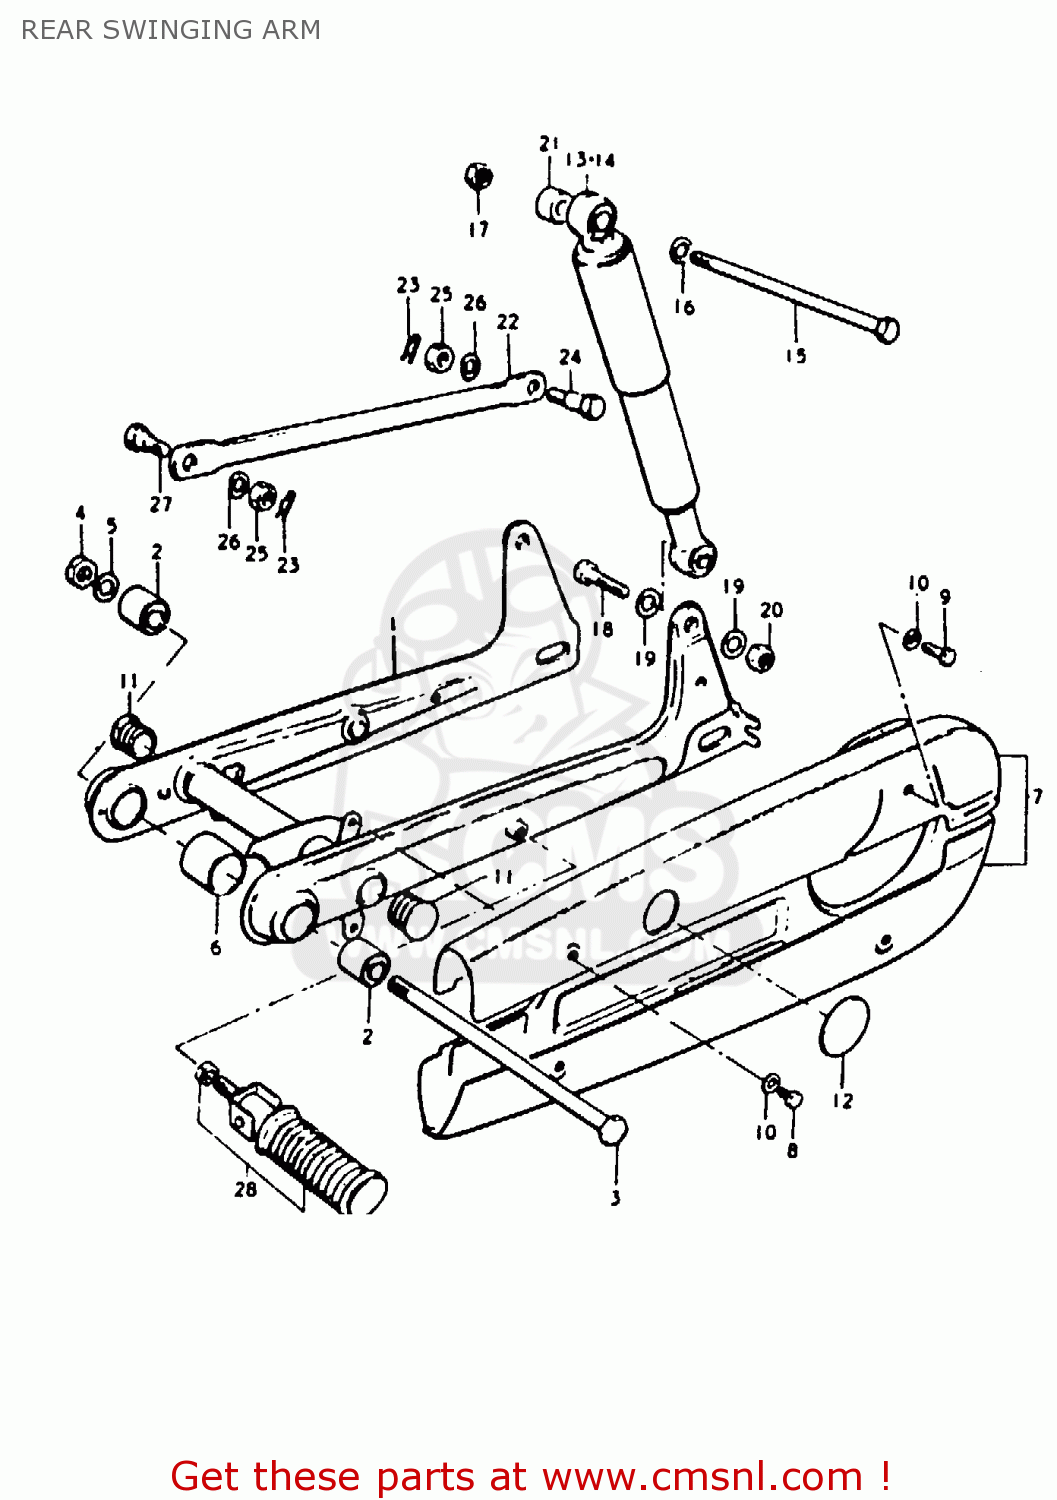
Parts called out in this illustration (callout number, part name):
1	SWINGING ARM, REAR
2	BUSHING(10X23X35)
3	SHAFT,REAR SWING ARM
4	NUT
5	LOCK WASHER
6	CUSHION
7	CHAIN CASE SET
8	BOLT(6X6)
9	BOLT
10	WASHER
11	CAP(OD:26)
12	CAP(OD:40)
13	ABSORBER ASSY,RR SHOCK
14	ABSORBER ASSEMBLY,REAR SHOCK
15	SHAFT,RR SHOCK ABSORBER UPR
16	WASHER
17	NUT
18	BOLT(10X43)
19	WASHER
20	NUT, LOWER LH
21	SPACER,SHOCK ABSORBER UPR
22	TORQUE LINK,REAR
23	CLIP
24	BOLT(8X26.5)
25	NUT
26	LOCK WASHER
27	BOLT(8X22.5)
28	FOOTREST ASSEMBLY,REAR
